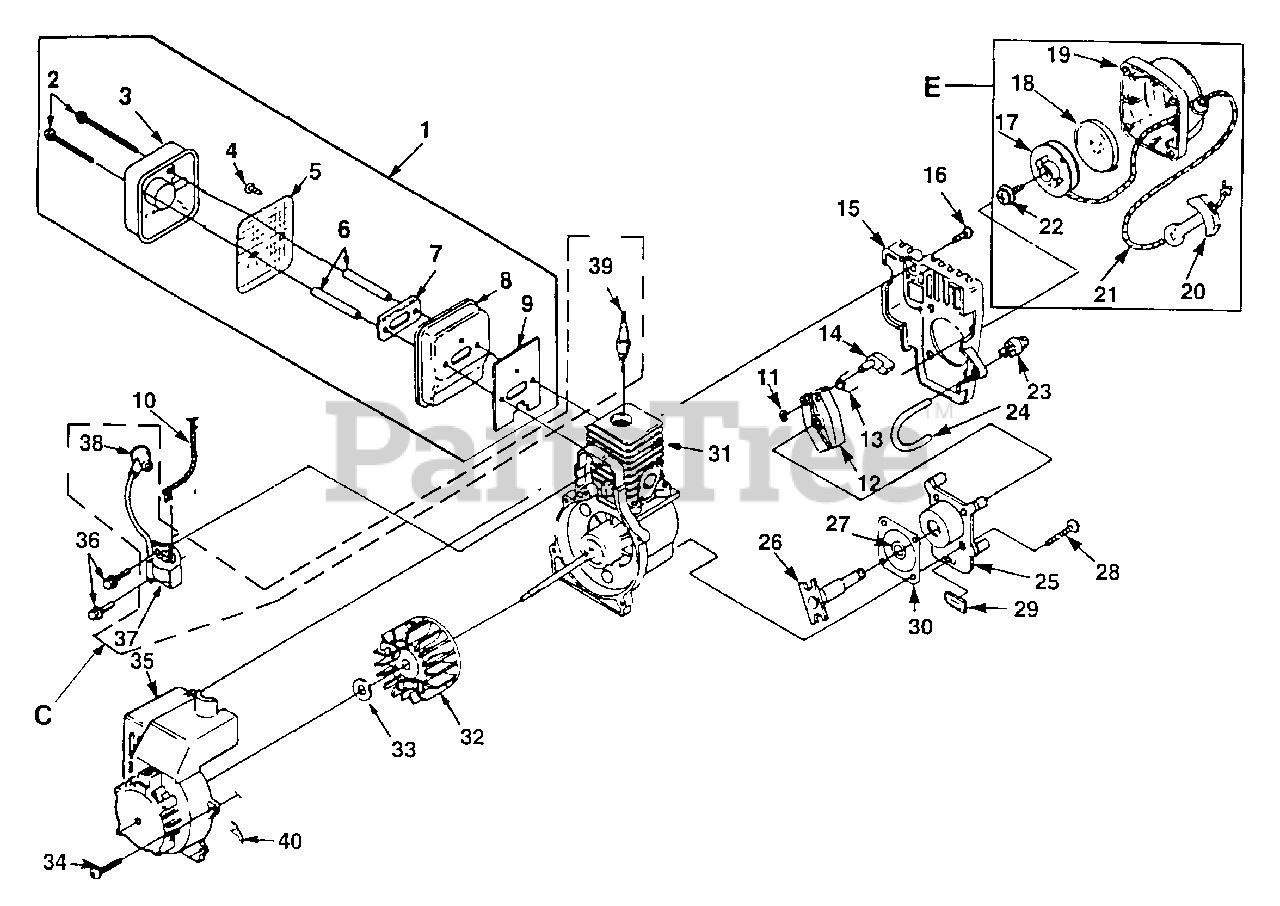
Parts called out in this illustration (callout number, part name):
1	MUFFLER-Complete
2	SCREW-Sems Hex Hd (10-24 X 2 1/5")
3	COVER-Muffler
5	SCREEN-Spark
6	SPACER-Muffler
7	PLATE-Reinforcing
8	MUFFLER BODY
9	GASKET-Muffler
10	LEAD-Electrical
11	RETAINING RING
12	CUP-Starter
13	SPRING-Starter
14	PAWL-Starter
15	COWLING-Engine
16	SCREW-Thread E Forming (#10 X 1/2")
17	PULLEY-Starter
18	SPRING-Recoil
19	HOUSING-Starter
20	GRIP-Starter
21	ROPE-Starter
22	SCREW-Set
23	BULB-Air Purge
24	RUBBER TUBING (8")
25	CRANKCASE COVER
26	SHAFT-Starter
28	SCREW-Thread Form (10-24 X 3/4")
29	BUMPER-Rubber
30	GASKET-Crankcase
31	SHORT BLOCK
32	ROTOR & STARTER PAWL
33	WASHER-Flat
34	SCREW-Thread Form (10-24 X 3/4")
35	HOUSING-Engine w/Decals
36	SCREW-Thread Form (8-32 X 1")
38	TERMINAL & COVER
39	SPARK PLUG (DJ-7Y)
40	TAB-Male
E	STARTER-Complete
C	IGNITION KIT
